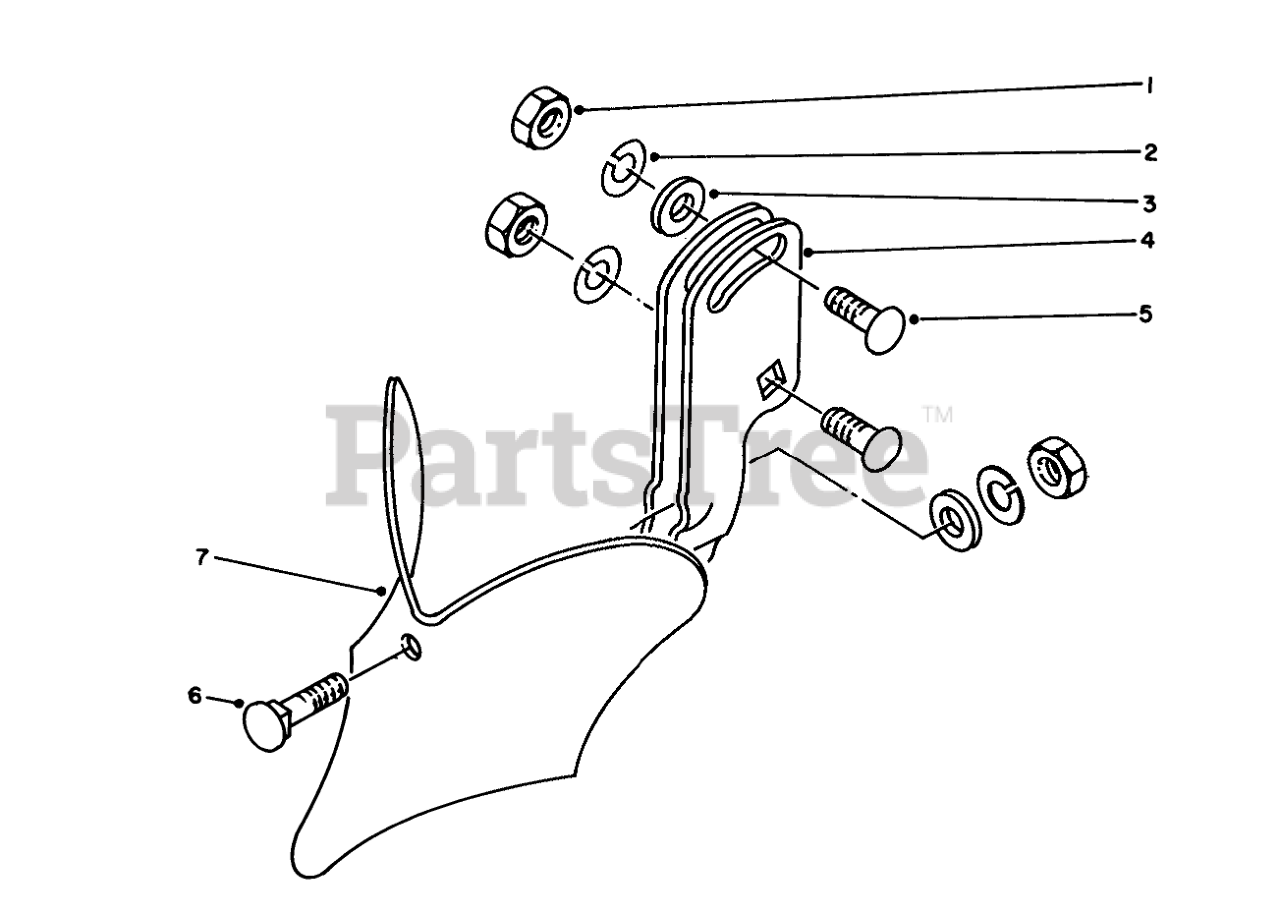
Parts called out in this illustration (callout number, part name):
1	NUT-HEX
2	WASHER-LOCK
3	WASHER-FLAT
4	Holder
5	BOLT-CARR
6	Plow Bolt
7	Shovel
